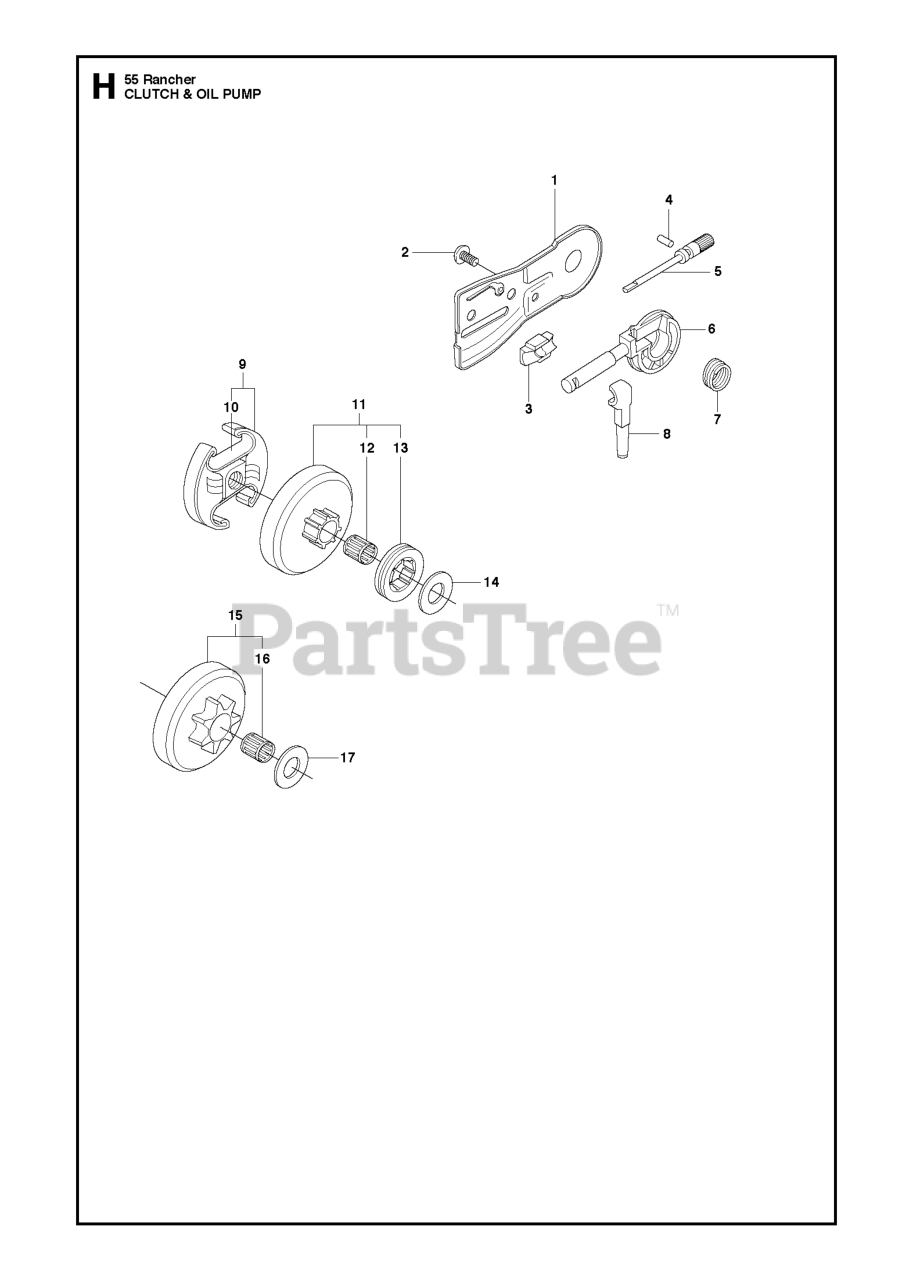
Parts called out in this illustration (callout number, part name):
1	CHAIN GUIDE PLATE
2	SCREW MC6S 5X16
3	PRESSURE SEAL
4	GROOVED PIN 3X20
5	PUMP PLUNGER
7	PUMP DRIVE WHEEL
8	SUCTION HOSE CPL
9	CLUTCH ASSY
11	DRUM 3/8X7 RIM
11	DRUM 325X7 RIM
12	SUPPORT BUSHING
13	RIM SPROCKET 3/8'' 7
13	RIM SPROCKET 7T .325
14	WASHER 12.7X30
15	CLUTCH DRUM 0.325X7
16	SUPPORT BUSHING
17	WASHER 12.7X30
